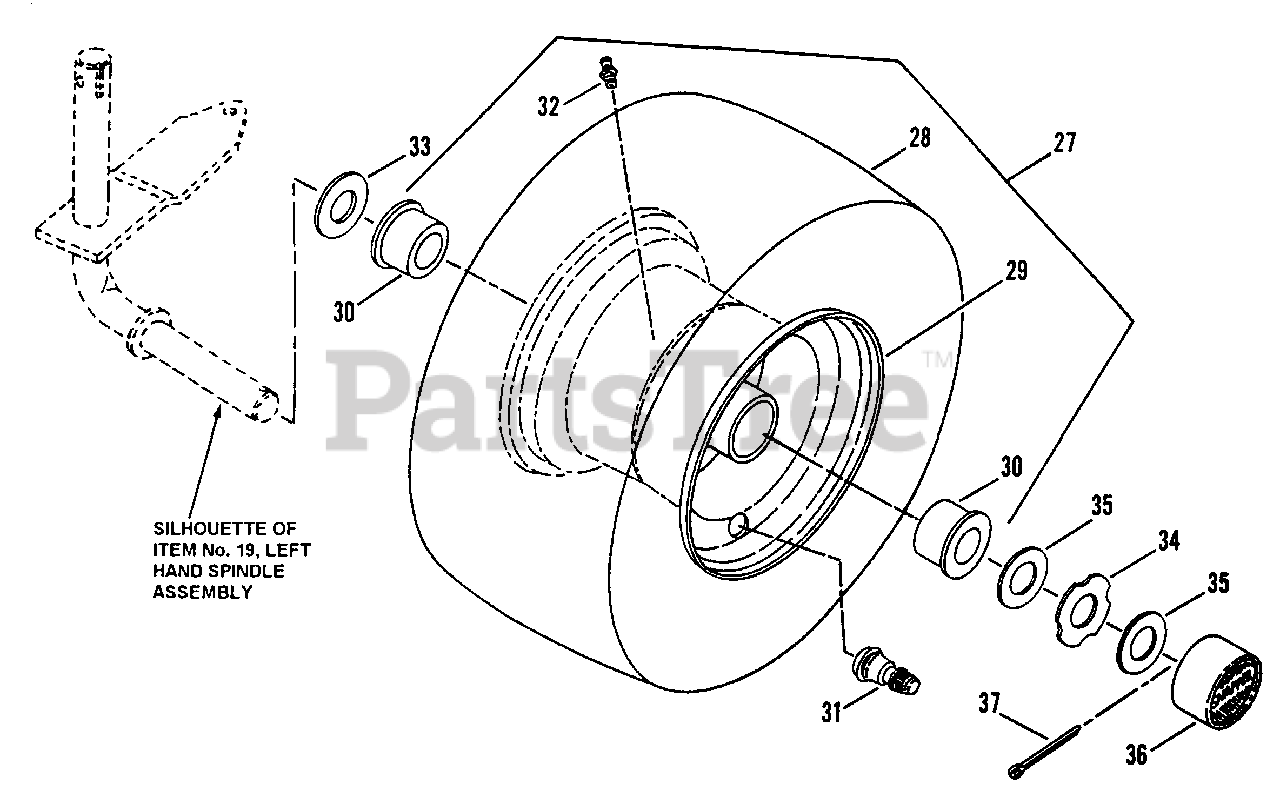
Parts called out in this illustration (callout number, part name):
27	ASSEMBLY, Front Tire & Rim, 30 & 33 Decks
27	ASSEMBLY, Front Tire & Rim, 38" & 42 Decks
28	TIRE, 13 x 5.00 (30" & 33" Decks)
28	TIRE, 15 x 6.00 (38" & 42" Decks)
29	RIM, 5.50 x 4.00
30	BEARING, Wheel
31	VALVE, Air (Snap-In)
32	FITTING, Lube 1/4-28 Tapered Thread
33	WASHER, Flat, .15 x .78 I.D. x 1.5 O.D.
34	WASHER, Hub-Cap Retaining
35	WASHER, Flat, .07 x .77 I.D. x 1.31" O.D.
36	HUB-CAP
37	COTTER-PIN, 5/32 x 1"
